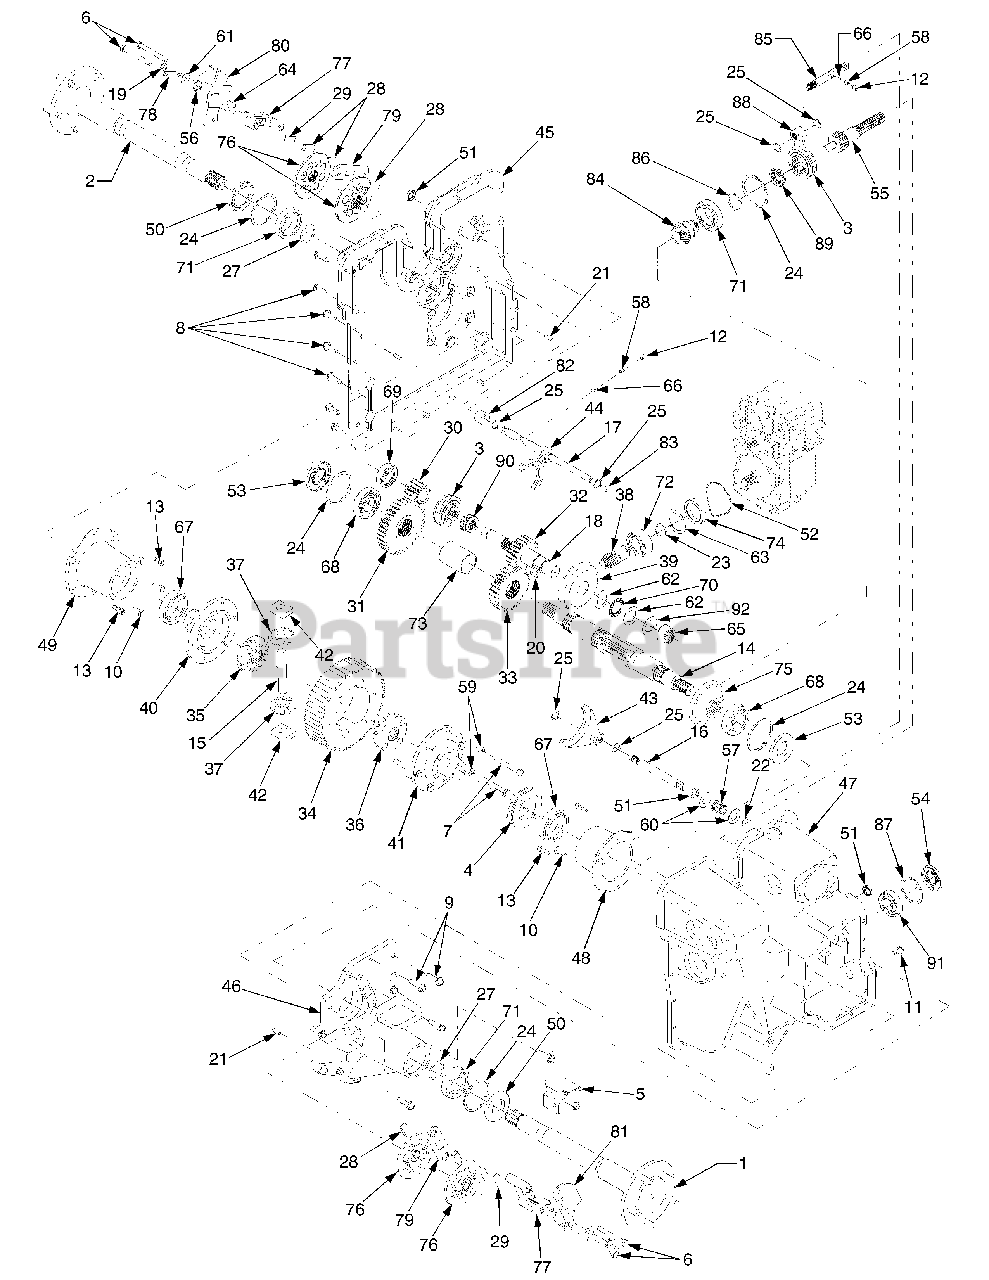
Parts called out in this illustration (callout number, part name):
1	Shaft, Axle RH
2	Shaft, Axle LH
3	Collar, Shift
4	Collar Assembly, Diff Lock
5	Bracket, Diff. Lock
6	Screw, Hex Cap, 5/16-18 x 2.75 GR5
7	Screw, Hex Cap, 5/16-18 x 2.5 GR5
8	Screw, Hex Wash. Hd. Tapp, 5/16-18 x 1.0
9	Screw, Hex Wash. Hd. Tapp, 5/16-18 x 1.25
10	Screw, Hex Cap, w/Patch 5/16-18 x .75GR5
11	Screw, Plug, M14 x 1.5 x .827
12	Screw, Set, 5/16-18 x .375
13	Screw, Shoulder .309 x .375: 1/4-20
14	Shaft, Output, 11T
15	Shaft, Cross, .625 x 3.95
16	Shaft, Diff. Lock Actuator
17	Shaft, Hi-Lo Actuator
18	Shaft, Drive
19	Nut, Hex Insert Lock, 5/16-24
20	Key, Woodruff, 1/4 x 3/4
21	Pin, Dowel, .25 x .75
22	Ring, Retaining
23	Ring, Snap
24	Ring, Retaining
25	Clip, Rotor
27	Ring, Retaining
28	Pad, Brake
29	Plate, Brake Puck
30	Gear, Spur, 12T : Low
31	Gear, Spur, 34T
32	Gear, Spur, 19T
33	Gear, Spur, 27T
34	Gear, Spur, 56T
35	Gear, Bevel, 16T
36	Gear, Bevel, 16T Lock
37	Gear, Bevel, 10T Diff.
38	Gear, Spiral Bevel, 13T
39	Gear, Spiral Bevel, 54T
40	Cover, Differential
41	Cover, Differential Lock
42	Block, Thrust
43	Yoke, Diff. Lock Actuator
44	Yoke, Shift, Hi-Lo
45	Cover, Trans. Large
46	Cover, Trans. Small
47	Housing, Trans.
48	Housing, Axle Inner - RH
49	Housing, Axle Inner - LH
50	Seal, Oil
51	Seal, Oil
52	Seal, Gland
53	Seal, Oil
54	Seal, Oil
55	Shaft, 4WD
56	Spring, Torsion
57	Spring, Compression, .845 x 1.0
58	Spring, Compression, .24 x .563
59	Washer, Lock, 5/16
60	Washer, Flat, .597 x 1.0 x .04 ..
61	Washer, Flat, .343 x .88 x .062
62	Washer, Thrust
63	Washer, Flat, 1.52 x 2.0 x .030
64	Pin, Brake Actuating
65	Bearing, Needle
66	Ball, Detent
67	Bearing, Ball
68	Bearing, Ball
69	Bearing, Ball
70	Bearing, Needle Thrust
71	Bearing, Ball
72	Bearing, Ball
73	Spacer, 1.51 x 1.75 x 2.41
74	Spacer, 1.515 x 2.039 x .335 ...
75	Gear, Spiral Bevel, 36T
76	Disc, Brake
77	Yoke, Brake
78	Bracket, Brake Anti Rotation
79	Plate, Puck Retainer
80	Arm, Brake Actuator - LH
81	Arm, Brake Actuator - RH
82	Spacer, .573 x .938 x .832
83	Plug, .437 x .16
84	Gear Assembly w/Bearings
84	Bearing, Sleeve, 13 x 15 x 10
85	Shaft, 4WD Actuator
86	Ring, Retaining
87	Ring, Retaining
88	Yoke, 4WD
89	Gear, Spline Coupling
90	Gear, Hi-Lo Spline Coupling
91	Bearing, Ball
92	Washer, Flat, 1.0 x 1.56 x .010 .
